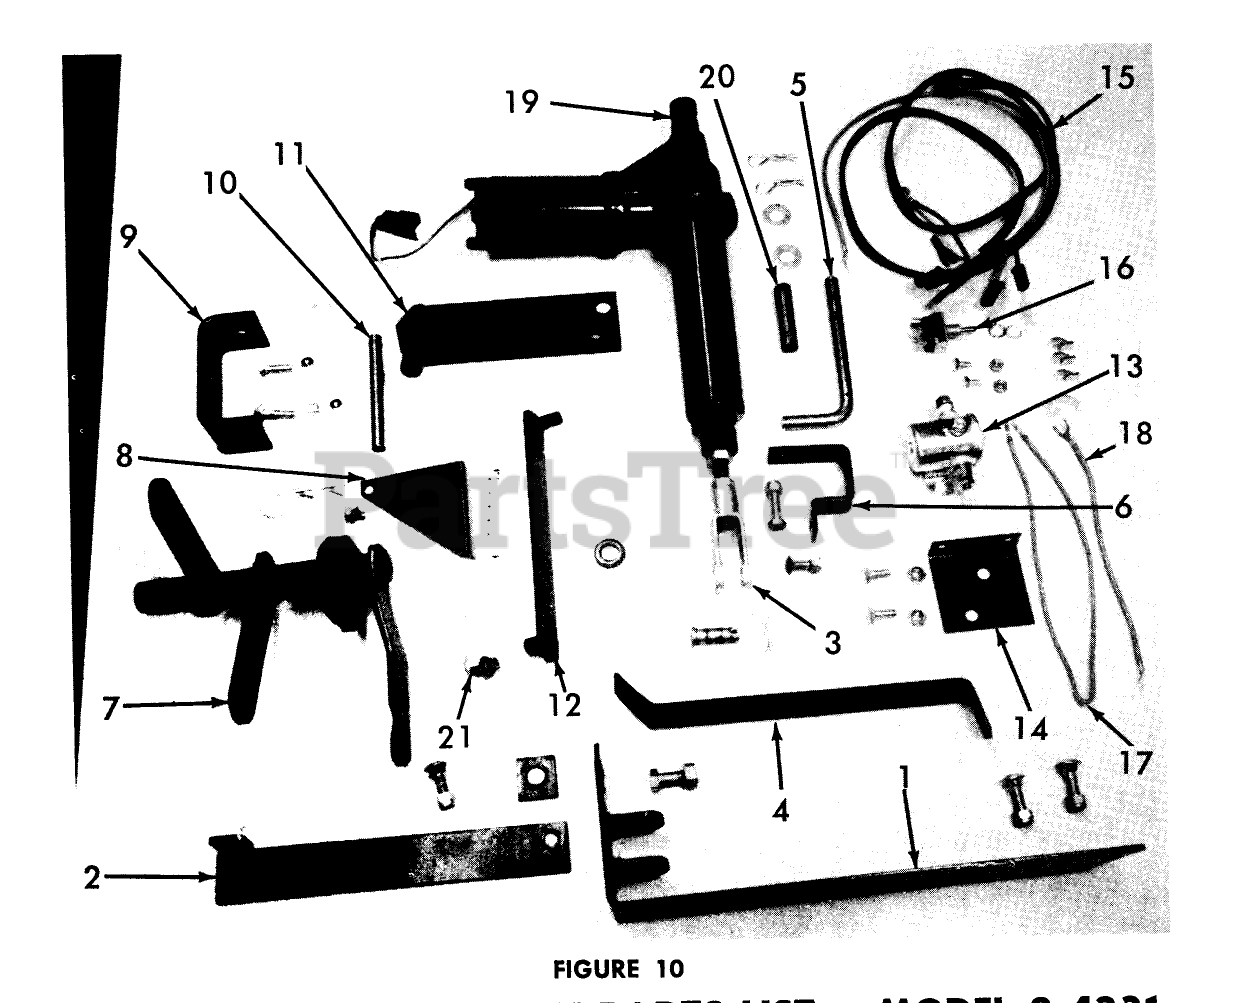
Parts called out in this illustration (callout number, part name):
1	Assembly-Rear Frame Mounting
2	Assembly-Bar-Upper Support
4	Brace-Mounting Frame
5	Pin-Anchor-Rear
6	Bracket Footrest
7	Assembly-Lift Arm
9	Bracket-Pivot Mounting
10	Pin-Pivot
11	Assembly-Pivot Arm
12	Assembly-Link
17	Wire-Accessory-to-Solenoid
20	Spacer-1/2 I.D. x 2 1/2
21	Arm
